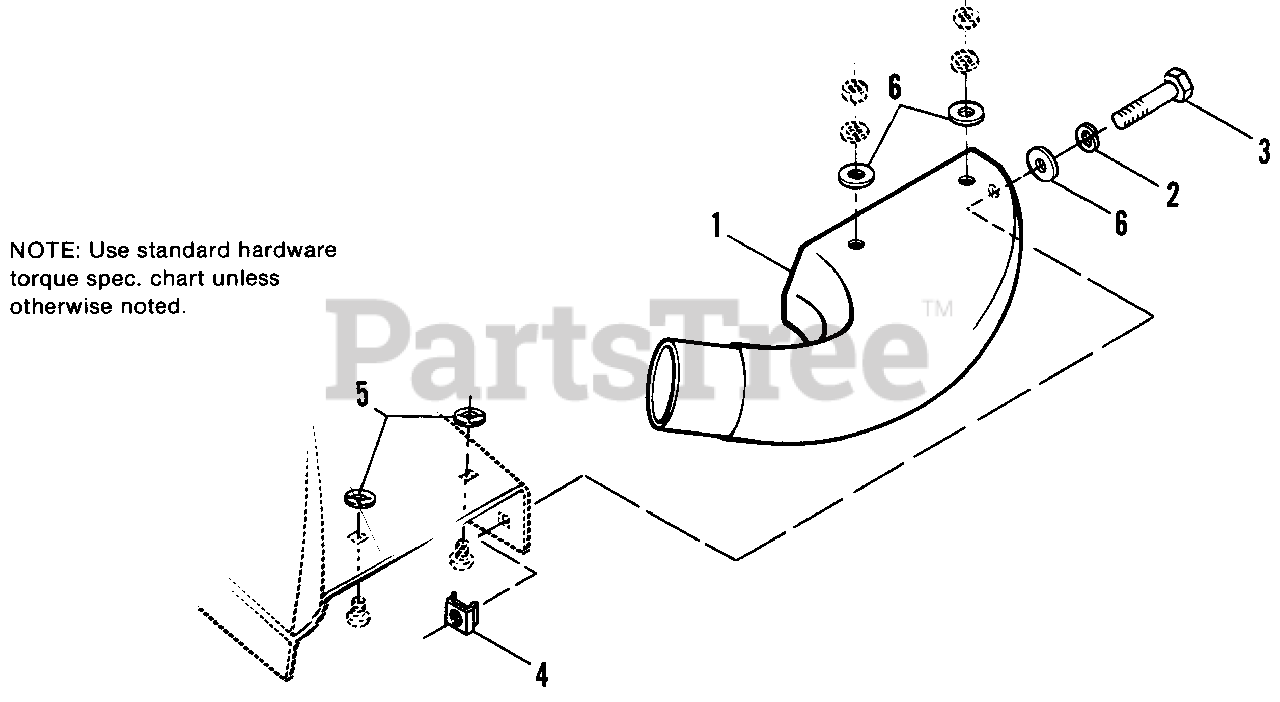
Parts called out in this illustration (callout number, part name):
1	ADAPTOR, 36" Mower
2	LOCKWASHER, Spring, 5/16
3	CAPSHCREW, Hex, 5/16-18 x 7/8
4	NUT, Retainer, 5/16-18
5	PUSHNUT, 3/8
6	WASHER
